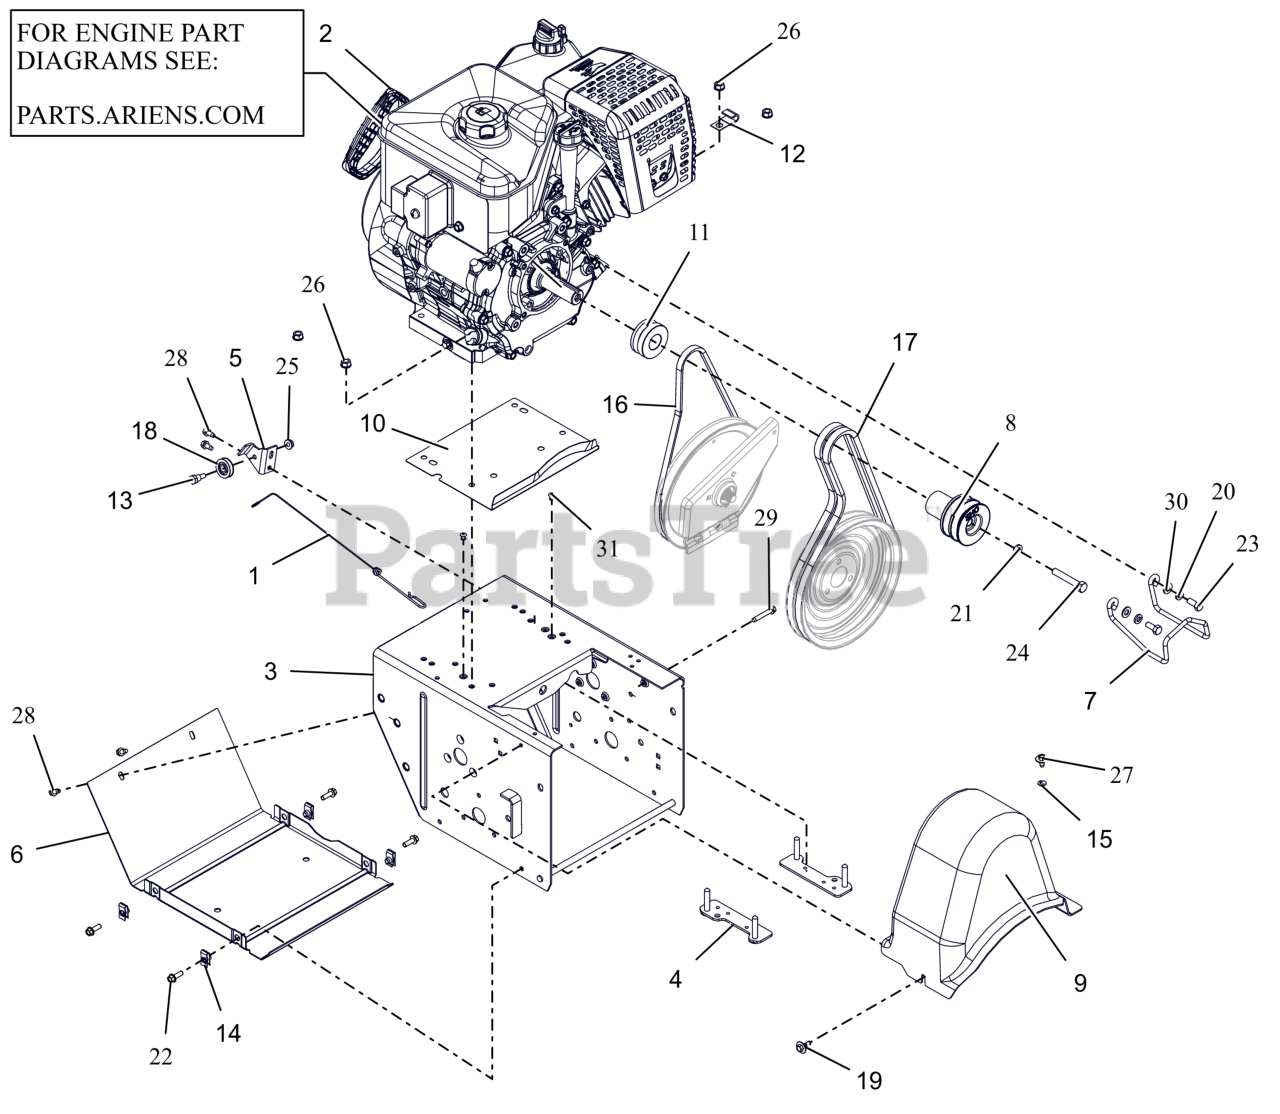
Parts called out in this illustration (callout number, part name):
1	CABLE, LOWER TRACTION,SS & PRO
2	ENGINE, AX420 GEN 3 120V/60W
3	FRAME, MAIN - PRO (WELDMENT)
4	STRAP, BOLT-LARGE
5	BRACKET, CABLE PULLEY
6	COVER, BOTTOM
7	FINGER, BELT
8	SHEAVE,ATTACHMENT-SHO 2 GRV
9	COVER, BELT-LARGE
10	BAFFLE, WATER - LARGE BLOCK
11	SHEAVE, TRACTION (KEYLESS)
12	J-CLAMP
13	BOLT, SHLDR -.375 X .375 X .25-20
14	NUT-RTNR .25-20X.56
15	NUT-PUSH .25X.50 O.D.
16	V-BELT, 3L-WRAPPED
17	V-BELT, HA-RAW EDGE (SET)
18	PULLEY, CABLE
19	SCR-TAP .25-20X.5 CAPTIVE
20	WSHR, LK-HVY .312X.097 ZCC
21	WSHR,LK-REG .375X.094 ZCC
22	BLT, HWH .25-20X.75 G5 ZCC
23	BLT, HEX .31-24X.750 G5 ZCC
24	BLT, HEX .38-24X2.25 G5 ZCC
25	NUT-LK-TOP-FLG .250-20 GF ZCC
26	NUT,LK-CTR-FLG .31-18 GF ZCC
27	SCR, TAP .25-20X.50 LG HWH ZCC
28	SCR-TAP .25-20X.50 HWH ZCC
29	SCR,TAP .25-20X1.50 HWH TR ZCC
30	WSHR,FLT .344X.688X.065 ZCC
31	RVT, POP .1875 ZCC
